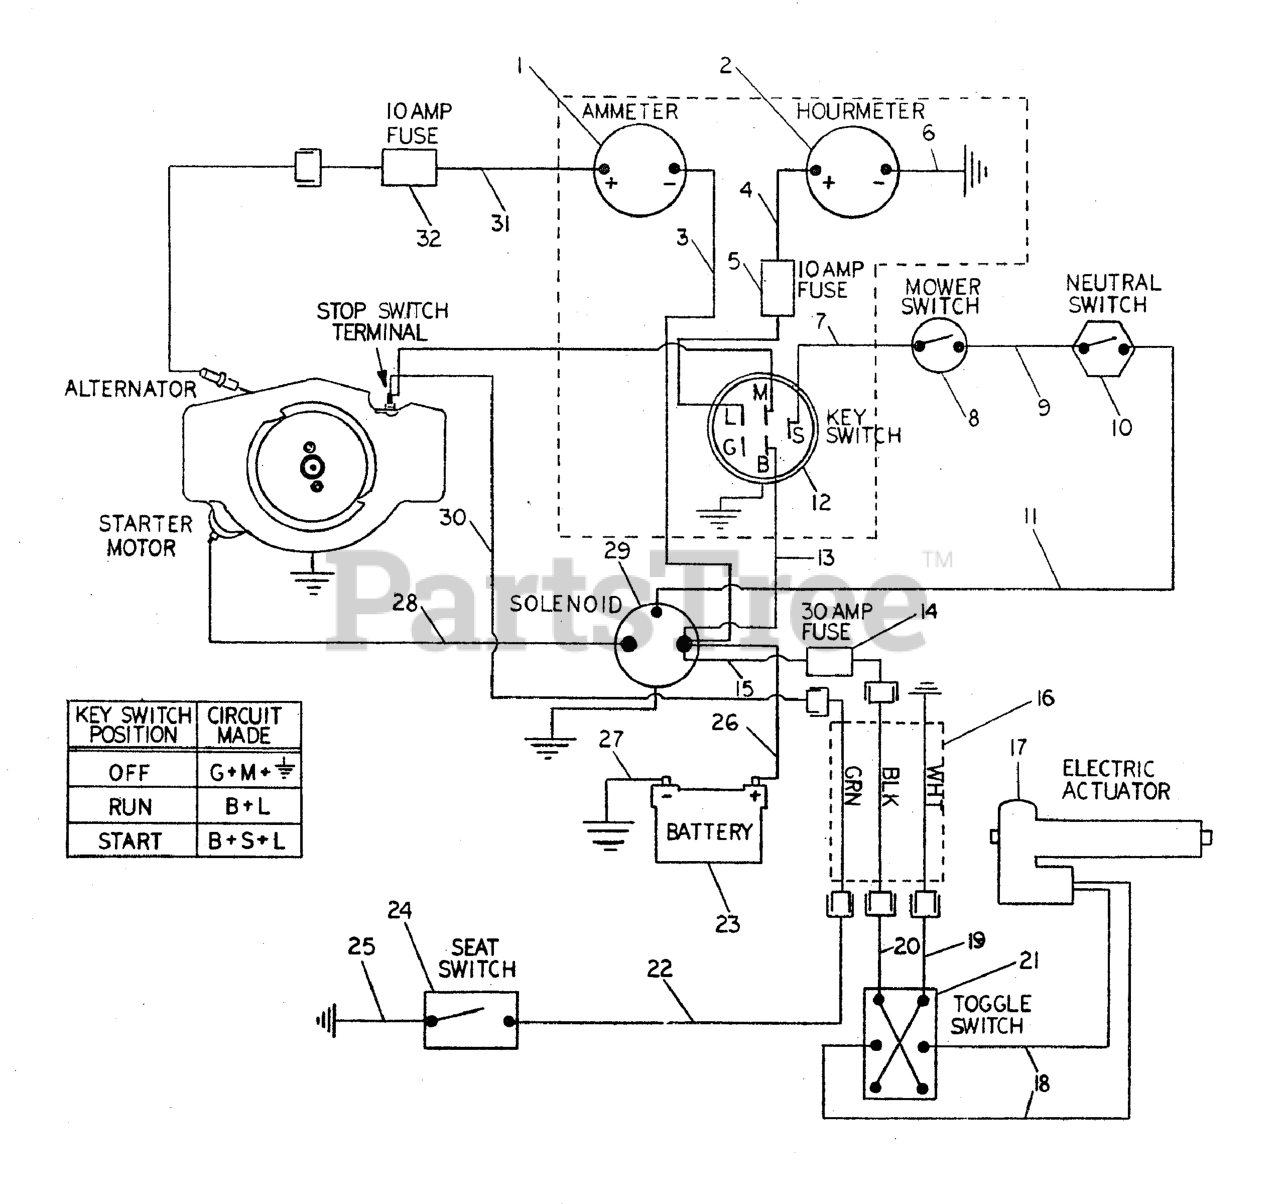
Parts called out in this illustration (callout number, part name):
1	Ammeter
2	HOUR METER
3	29" Long #14 Wire Assembly
4	9" Long Fuse Holder Wire Assembly
5	10 Amp Fuse
6	4" Long #14 Wire Assembly
7	32" Long #14 Wire Assembly
8	Safety Switch
9	21" Long #14 Wire Assembly
10	Neutral Safety Switch
11	42" Long #14 Wire Assembly
12	SWITCH, Ignition
13	31" Long #14 Wire Assembly
14	30 Amp Fuse
15	9" Long Fuse Holder Wire Assembly
16	Alpha Cable
17	Electric Actuator
18	20" Long #14 Wire Assembly
19	12" Long #14 Wire Assembly
20	12" Long #14 Wire Assembly
21	Toggle Switch
22	39" Long #14 Wire Assembly
23	BATTERY, 11U1L, 350 CCA
24	Seat Switch
25	6" Long #14 Wire Assembly
26	18" Long #6 Wire Assembly
27	12" Long #6 Wire Assembly
27	Red Rubber Boot
28	21" Long #6 Wire Assembly
29	SOLENOID, Starter
30	28" Long #14 Wire Assembly
31	9" Long Fuse Holder Wire Assembly
32	10 Amp Fuse
